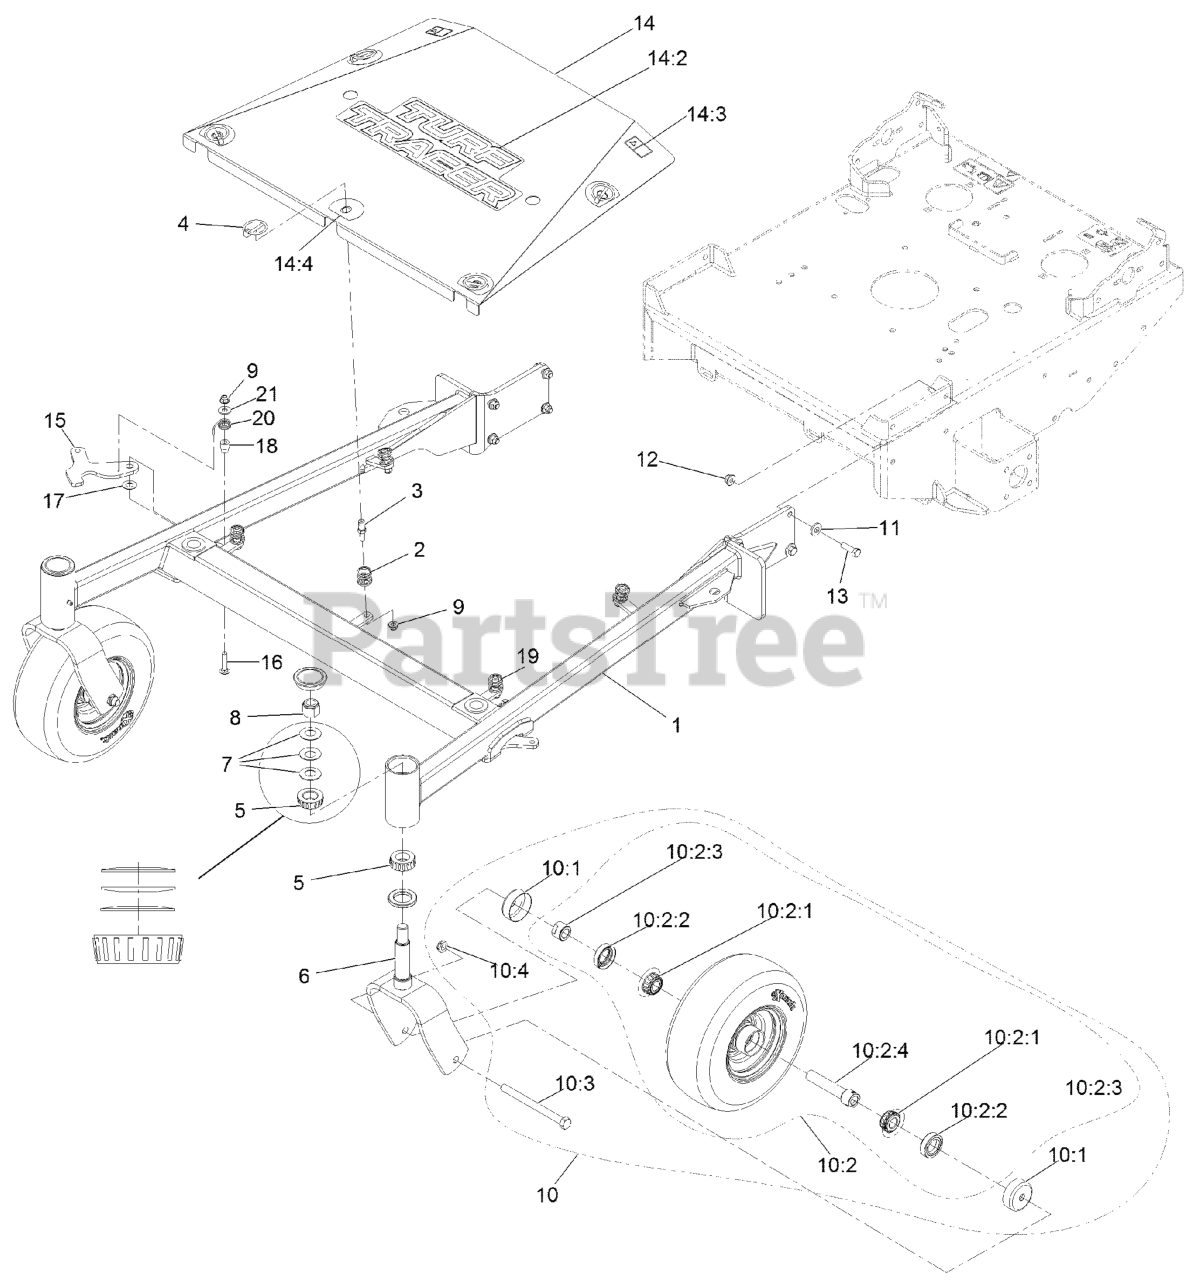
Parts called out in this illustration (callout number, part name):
1	ASM, FRONT FRAME W/ BEARI
3	PIN-SPRING
4	PIN-LYNCH
5	Cone-Bearing Tapered Roller
6	WLD, CASTER FORK
7	WASHER-BELLVILLE
8	NUT-LOCK, NI
9	NUT-HF, NI
10	ASM,WHEEL&BEARINGS
10:1	GUARD-SEAL
10:2	Wheel And Bearing ASM
10:2:1	BEARING-CONE, TAPERED ROLLER
10:2:2	SEAL-CASTER
10:2:3	SPACER-NUT
10:2:4	CASTER AXLE ASM
10:3	SCREW-HH
10:4	NUT-HEX
11	WASHER-BELLEVILLE
12	NUT-HF, NI
13	SCREW-HH
14	ASM, CENTER SHIELD W/ DEC
14:2	DECAL-TURF TRACER
14:3	DECAL-WARNING
14:4	DECAL-SCRATCH COVER
15	LATCH, DECK HEIGHT
16	BOLT-CARR
17	Washer-Plastic
18	Collar-Basket
19	Spring-Torsion, LH (Yellow)
20	Spring-Torsion, RH
21	WASHER-FLAT
